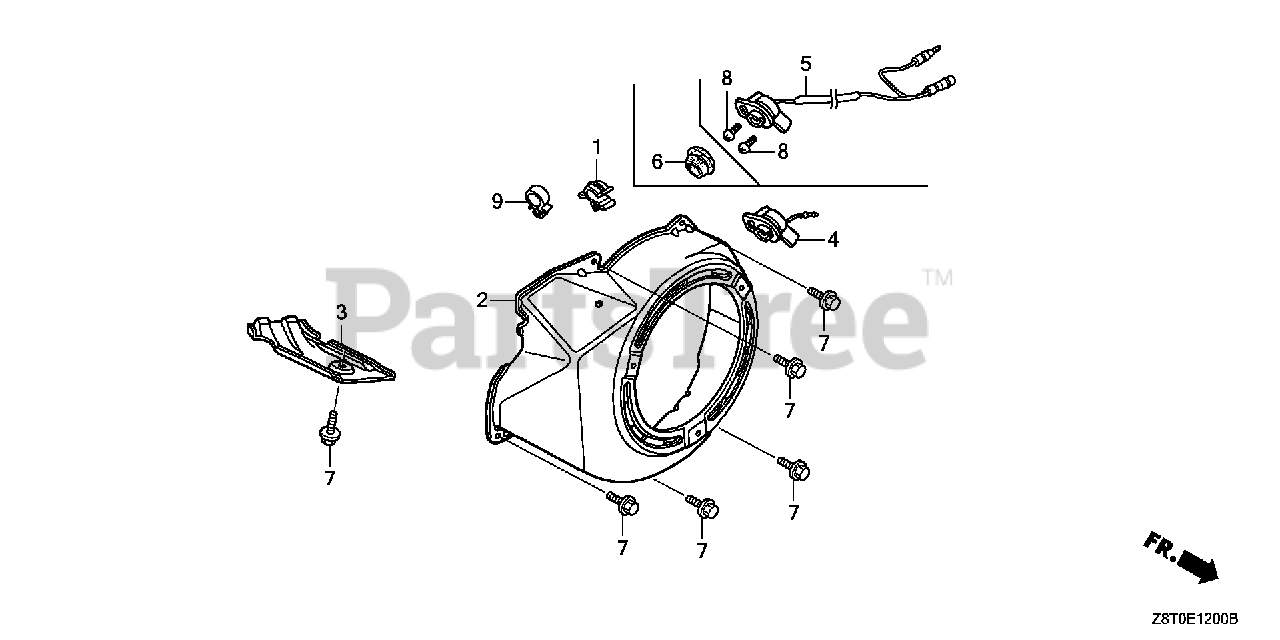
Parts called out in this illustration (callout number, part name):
1	CLIP, TUBE
2	COVER, FAN *R280* (POWER RED)
2	COVER, FAN *NH1* (BLACK)
5	SWITCH ASSY., ENGINE STOP
7	BOLT, FLANGE (6X12) (CT200)
8	SCREW, TAPPING (3X6) (PO)
